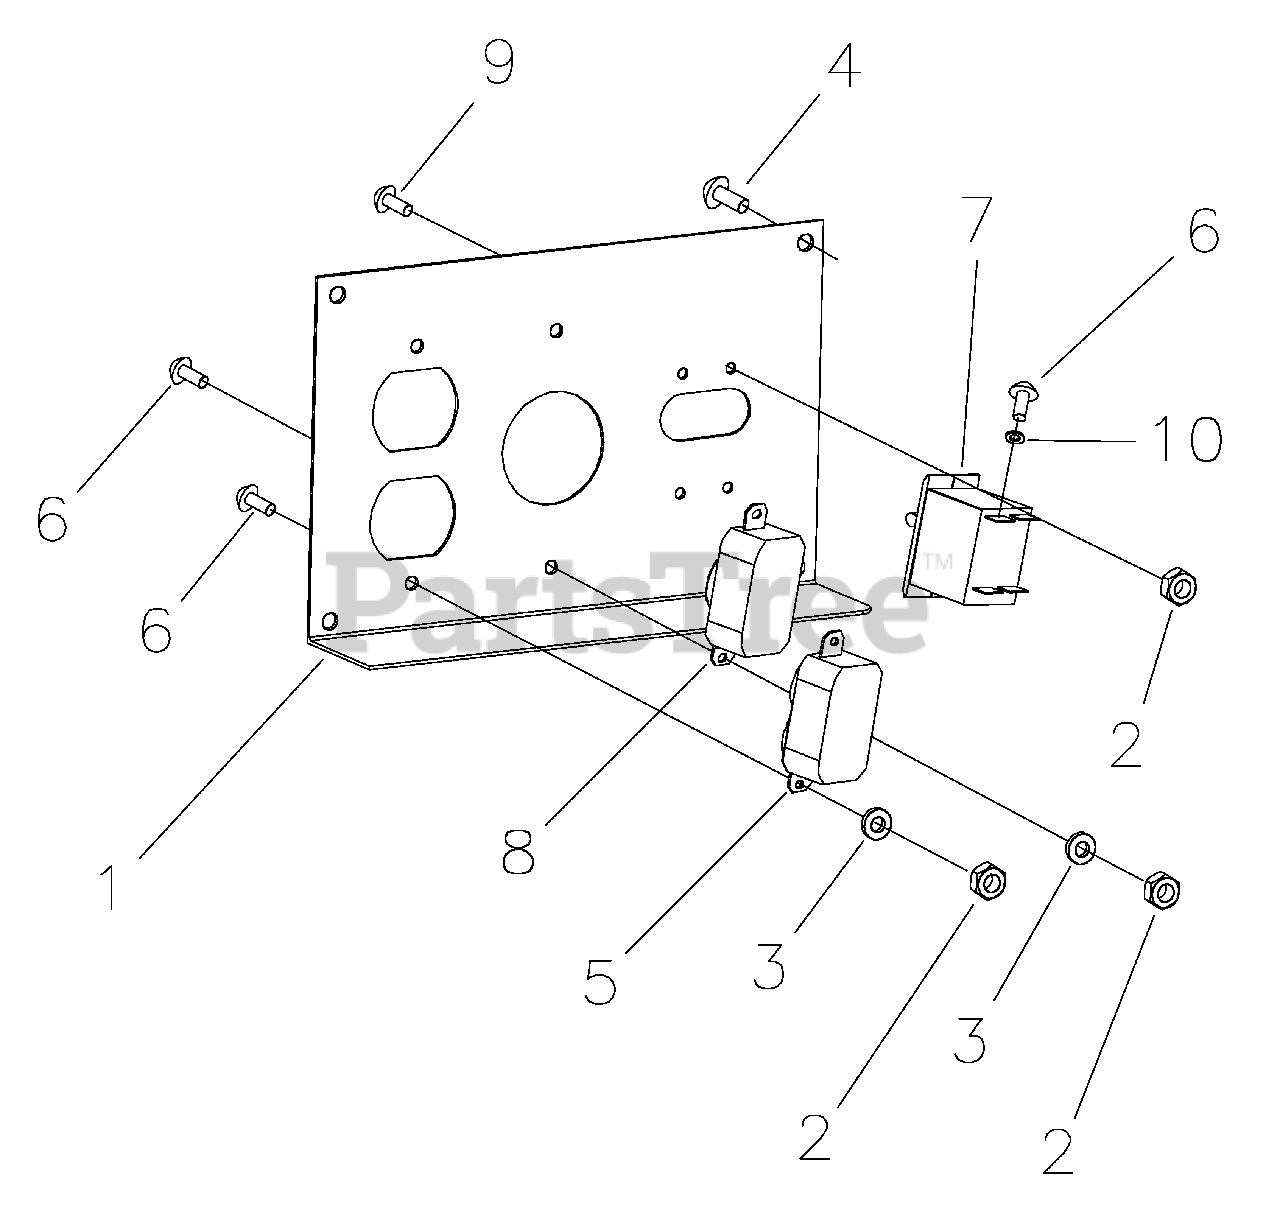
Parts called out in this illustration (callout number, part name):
1	Control Panel
2	Nut, Nylon
3	Washer, M4 x 08
4	Screw, M6 x 16
5	Outlet, 120/125V, 15/20a, Duplex
6	Screw, Pan Head, M4x10
7	Circuit Breaker, 15A
8	Outlet, 120/240V, 20a, Locking
9	Screw, M3 x 06
10	Lock Washer
